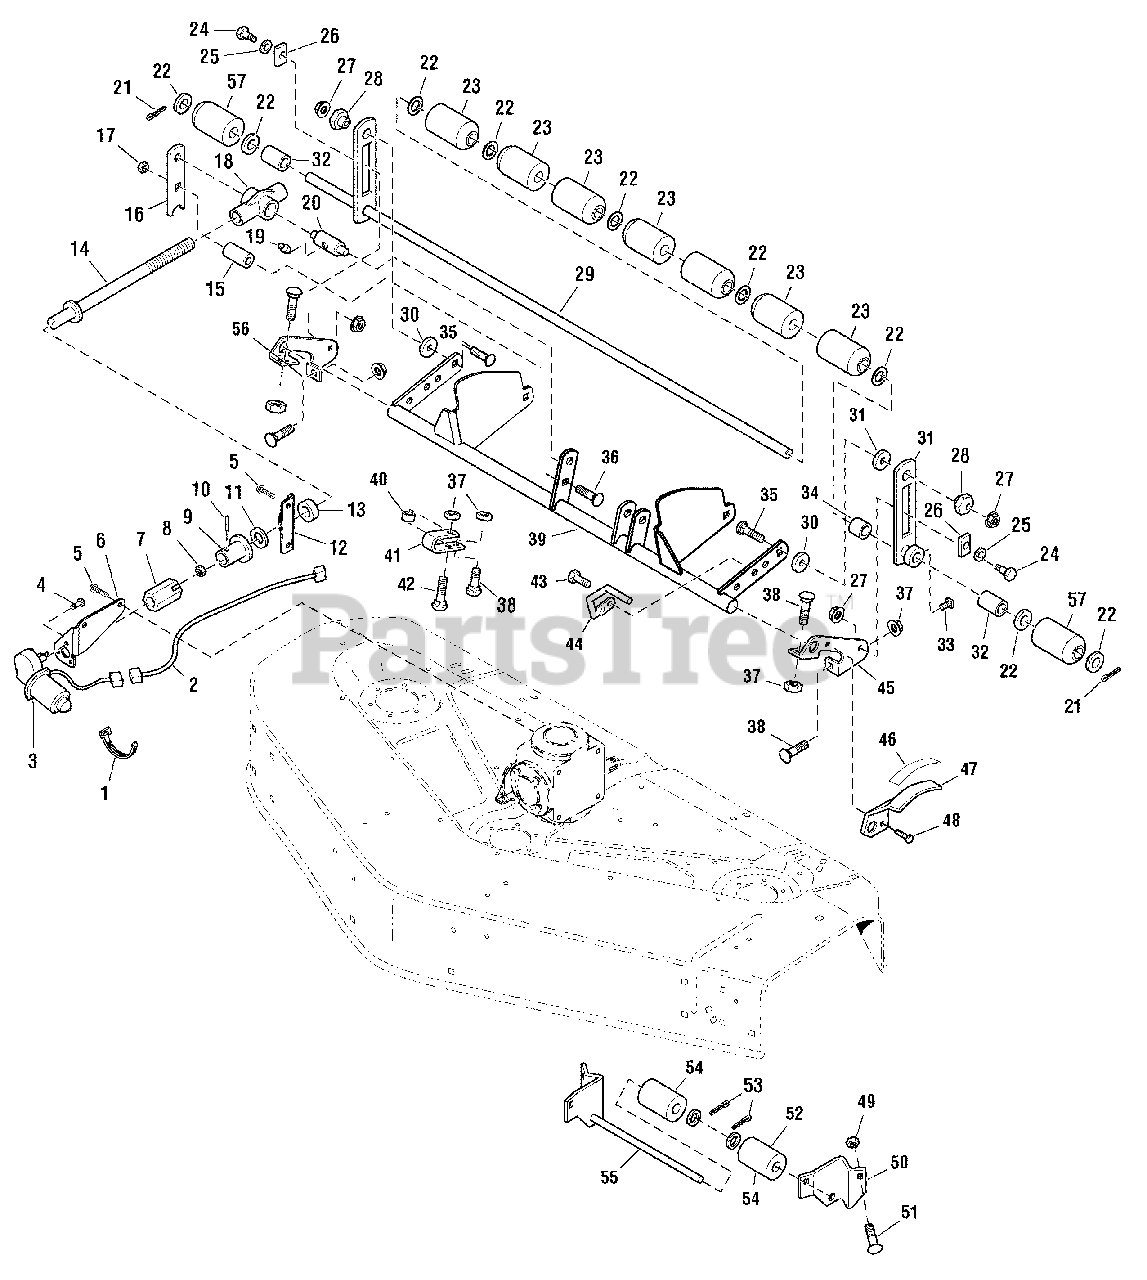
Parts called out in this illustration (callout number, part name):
1	TIE, Self Locking
2	HARNESS ASSEMBLY
3	MOTOR, Electric
4	CAPSCREW, Hex, SEMS Washer Head, Dog Point, 1/4-20 x 7/8
5	CAPSCREW, Hex Wsher Head, 3/8-16 x 1-1/8, Black
6	BRACE, Height of Cut
7	ADAPTER, Motor
8	NUT, Hex, KEPS, 1/4-20, Black
10	PIN, Spring
11	WASHER, Special
12	SUPPORT, Height of Cut
13	BEARING, Thrust
14	ROD & SPACER ASSEMBLY
17	NUT, Hex, Toplock Flange,1/2-13, Black
18	COVER, Rod, Black
19	FITTING, Grease
21	PIN, Cotter
22	WASHER, 1/2 x 1-1/4
23	ROLLER
24	BOLT, Shoulder, 3/8-16 X 1.34
25	WASHER, 1/2 x 1-1/4
27	NUT, Hex Toplock, 3/8-16
28	NUT, Hex Adjusting, .99 DIA .687
29	BAR & SHAFT ASSEMBLY, Roller
30	WASHER, 3/8
31	BAR ASSEMBLY, Roller, LH
32	SPACER, Long
33	SET SCREW, Square Head, 5/16-18 x 1/2, G8
34	SPACER, Short
35	CARRIAGE BOLT, 3/8-16 x 1-3/4
36	CARRIAGE BOLT, 1/2-13 x 2-1/2, Black
37	NUT, Hex, KEPS, 3/8-16 , Black
38	CARRIAGE BOLT, 3/8-16 x 1
39	ROCKER SHAFT ASSEMBLY
40	SPACER
42	CARRIAGE BOLT, 3/8-16 x 2-1/2, Black
43	CAPSCREW, Hex Head, Taptite, 5/16-18 x 1/2
44	ROD, Indicator
45	BRACKET, Roller, LH
46	DECAL, Height of Cut
47	PLATE, Height Indicator
48	CAPSCREW, Hex Washer Head, Taptite, 1/4-20 x 3/8
49	NUT, Hex,KEPS, 5/16-18, Black
50	BRACKET, Roller, LH
51	CARRIAGE BOLT, 5/16-18 x 3/4, Black
53	PIN, Cotter, Black
54	WASHER, 5/8, Black
55	BRACKET & SHAFT ASSEMBLY
56	BRACKET, Roller, RH
